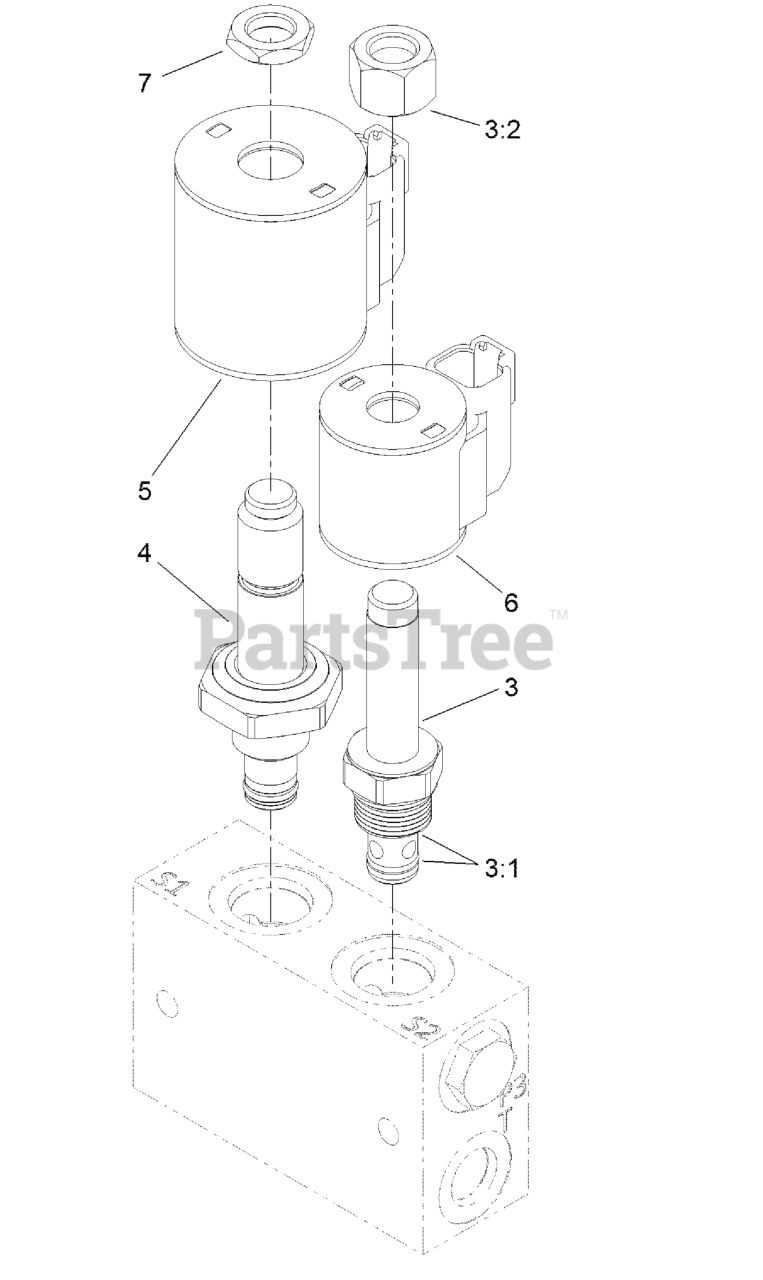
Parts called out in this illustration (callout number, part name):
3	VALVE-SOLENOID
3:1	SEAL KIT
3:2	NUT-SOLENOID
4	VALVE-SOLENOID
5	COIL-12V
7	NUT-COIL
